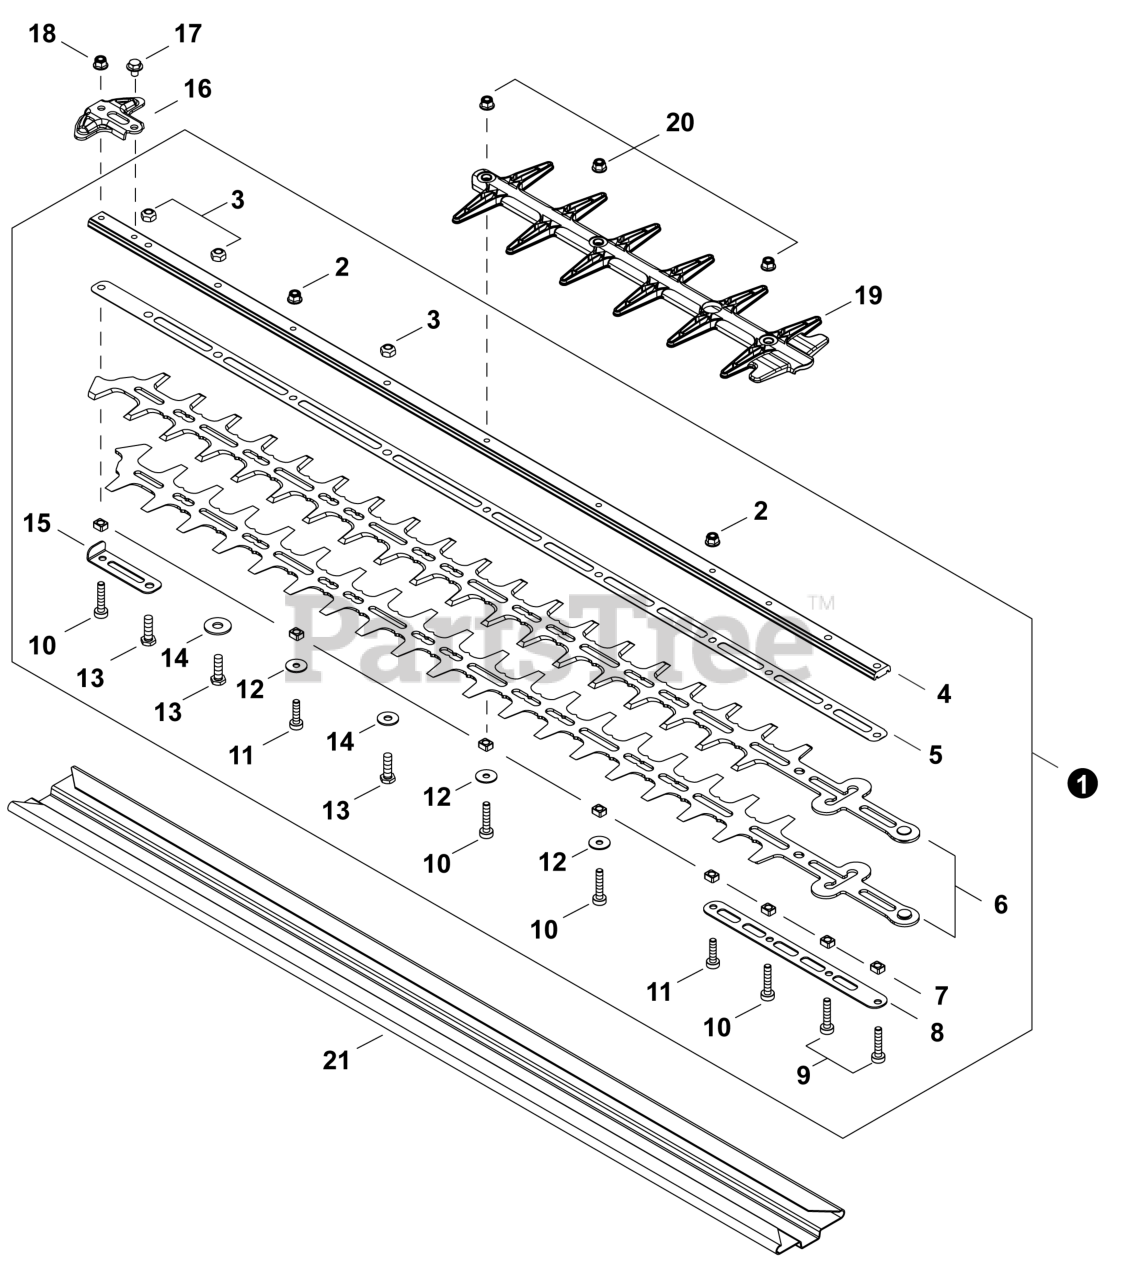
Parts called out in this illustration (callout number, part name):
1	CUTTER ASSY, 30"
2	NUT, FLANGE M5
4	SUPPORT, CUTTER 30"
5	PLATE, CUTTER 30"
6	CUTTER 30"
7	GUIDE, BLADE
8	PLATE, CUTTER
9	BOLT, TORX 5x25
10	BOLT, TORX 5x25
11	BOLT, TORX 5x20
13	BOLT M6x20
14	WASHER M6
15	PLATE, EYE
16	GUARD, TIP
18	NUT, FLANGE M5
19	GUARD, CUTTER BLADE
20	NUT, FLANGE M5
21	SCABBARD 30"
